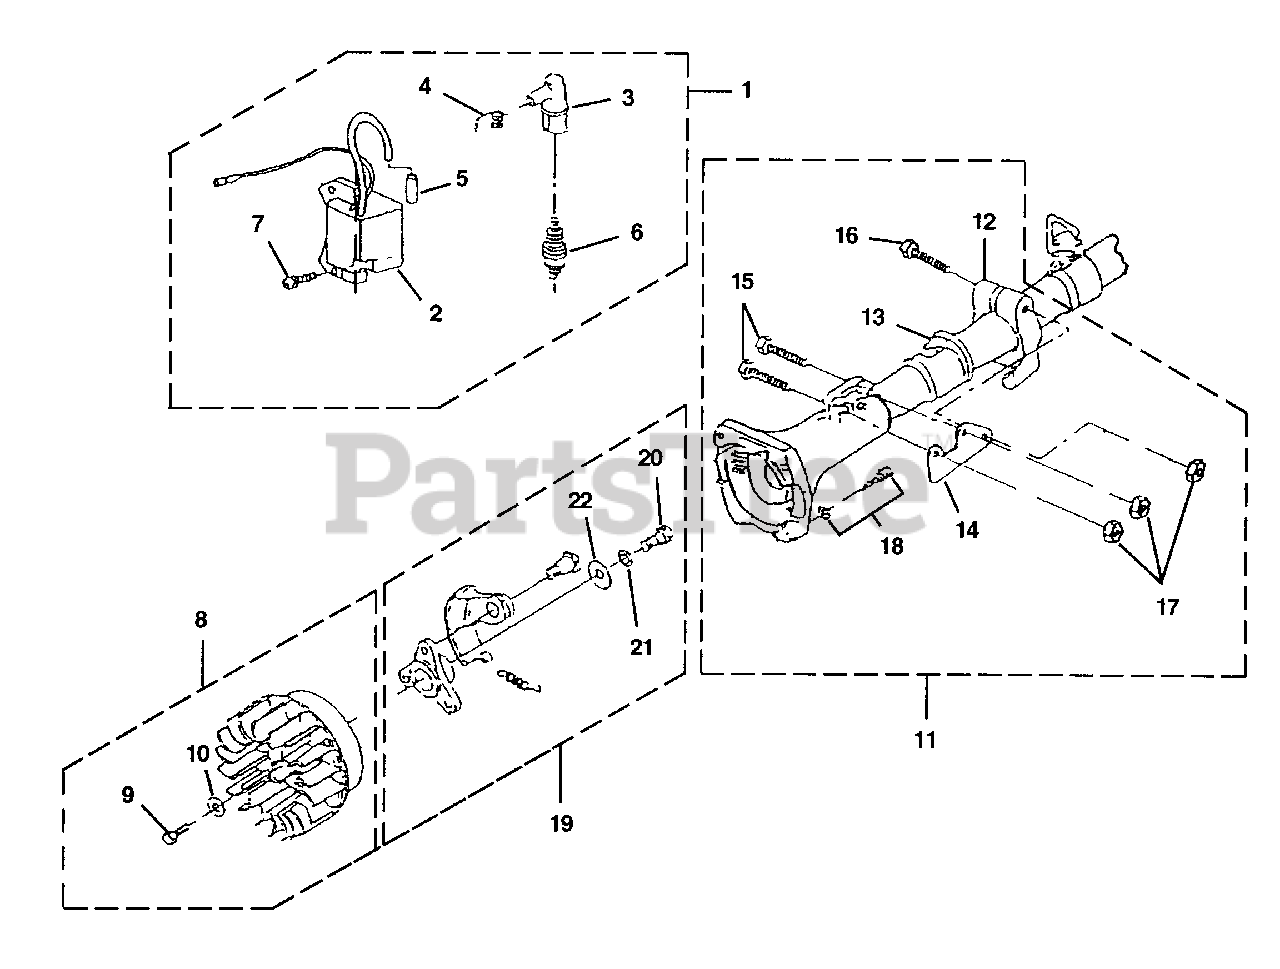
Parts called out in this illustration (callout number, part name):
1	IGNITION KIT
2	MODULE - Ignition
3	CAP - Plug
4	SPRING-Plug Cap
6	SPARK PLUG
7	SCREW-Socket Hd (MS x 22 W)
8	ROTOR ASSEMBLY
9	BOLT
11	CLUTCH HOUSING
18	SCREW-Socket Hd (M6 x 18 SW)
19	CLUTCH ASSEMBLY
20	BOLT
21	WASHER-Spring
